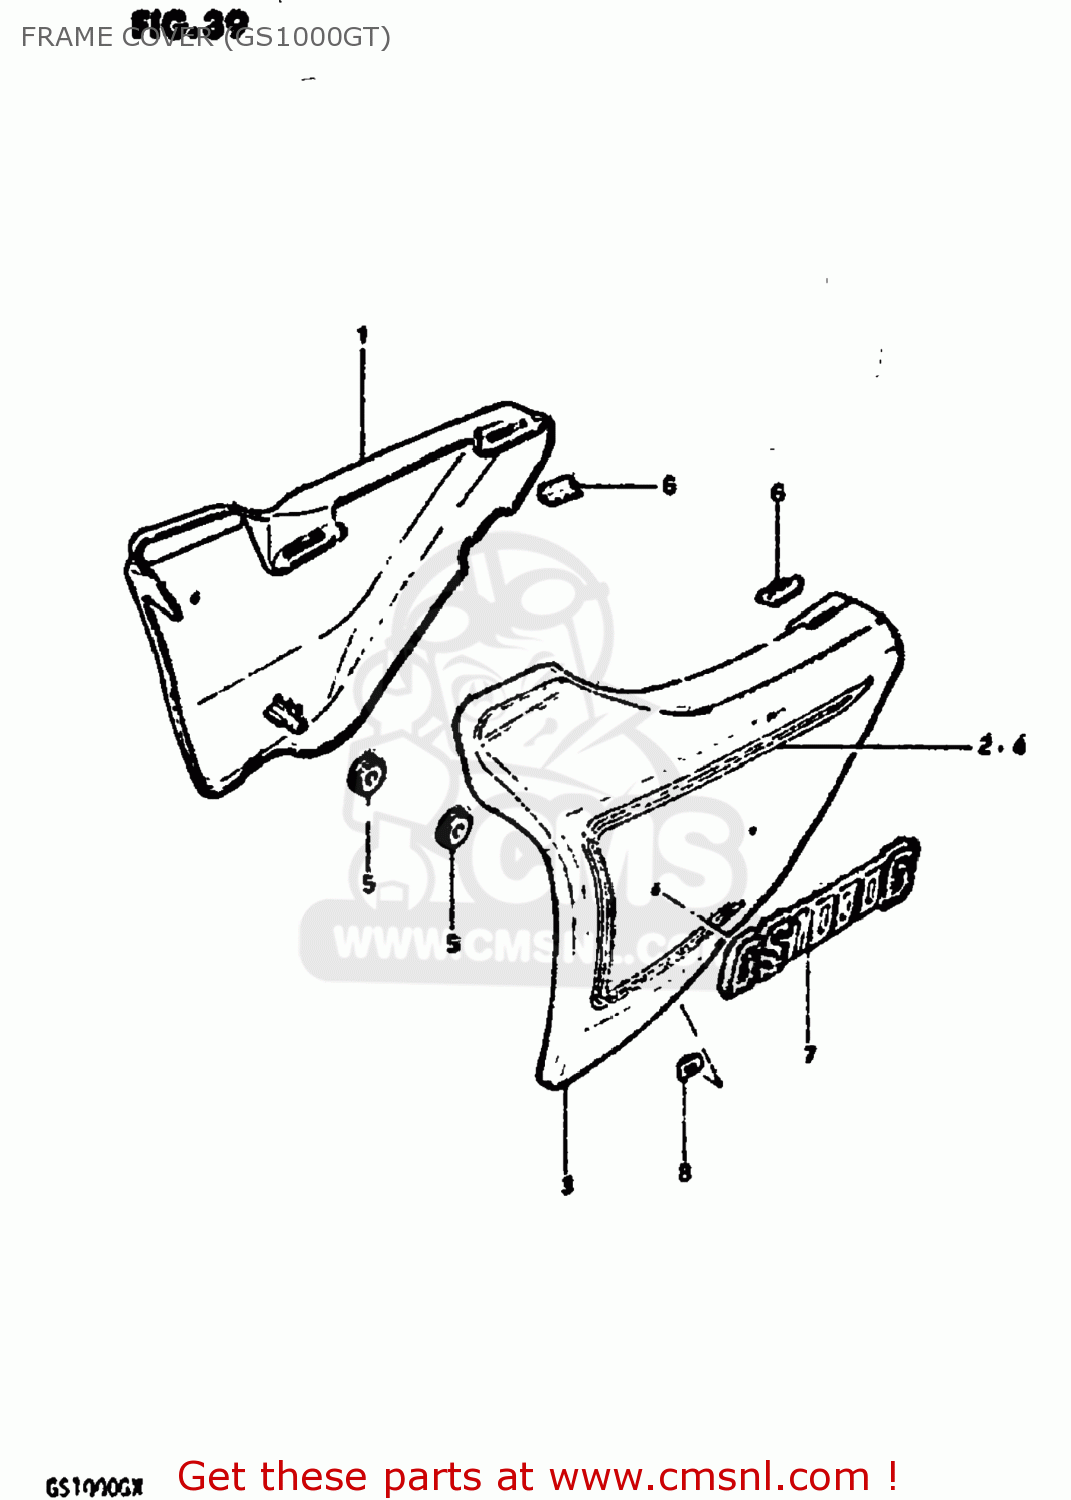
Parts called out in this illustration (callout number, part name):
1	COVER,FRAME,RIGHT
2	TAPE,FRAME COVER
3	COVER,FRAME,LEFT
4	TAPE,FRAME COVER
5	CUSHION
6	CUSHION,FRAME COVER
7	EMBLEM,FRAME COVER
8	NUT
